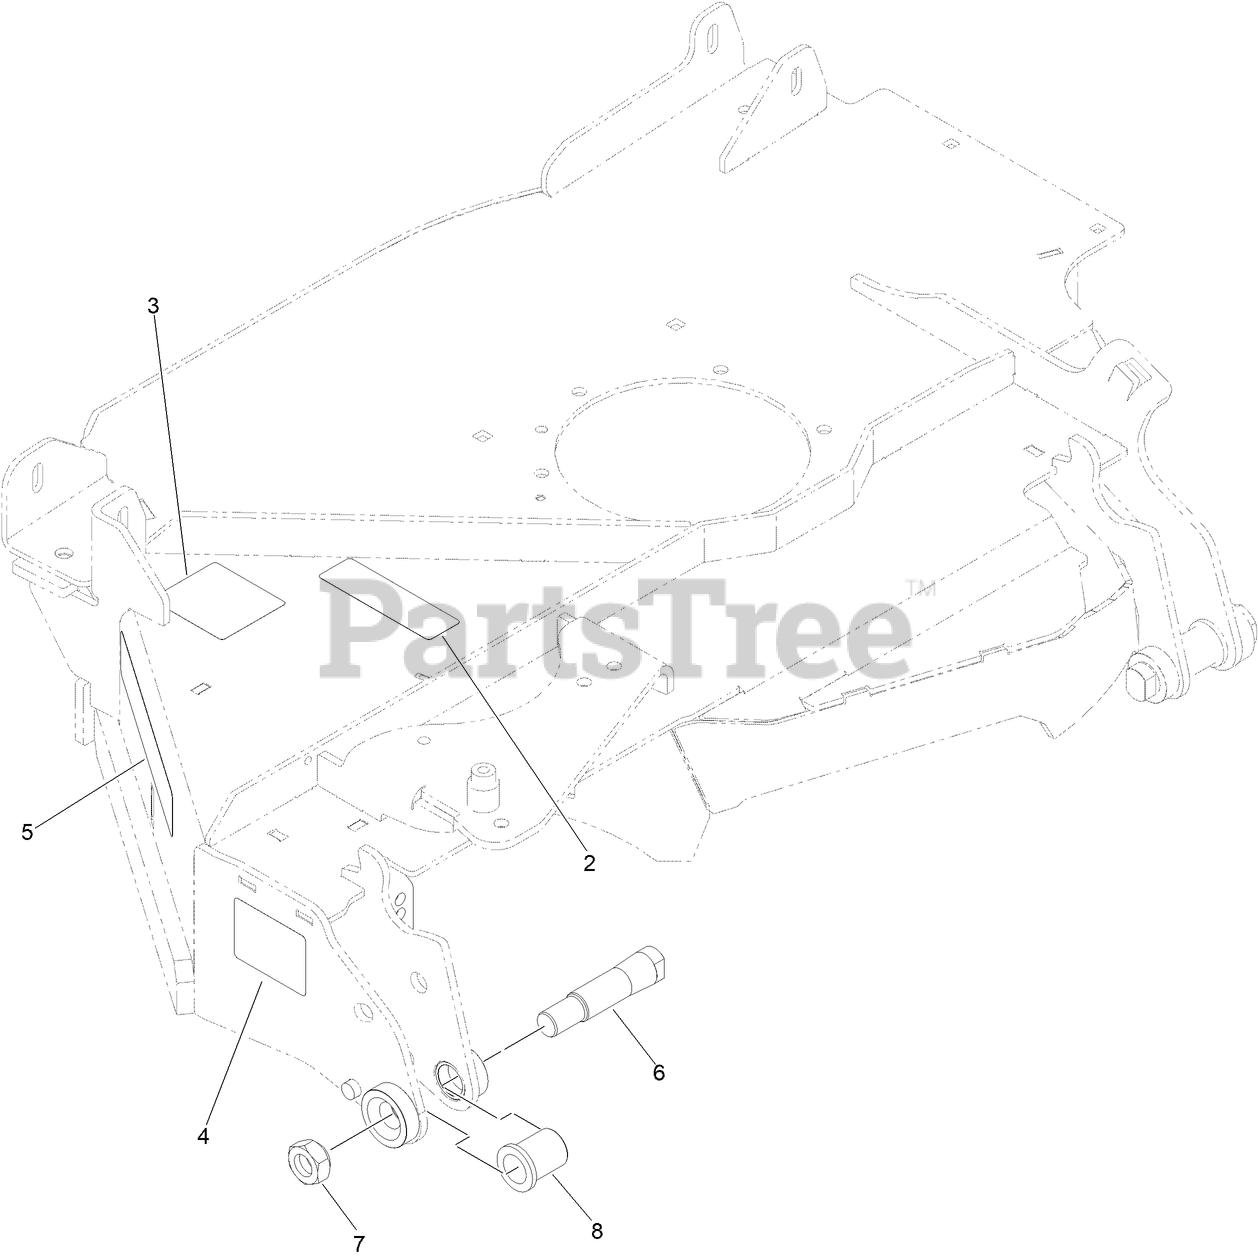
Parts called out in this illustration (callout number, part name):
2	DECAL-COVER, MISSING
3	DECAL-DANGER, THROWN OBJECT
4	DECAL-WARNING, PINCH POINT
6	BOLT-PIVOT PIN
7	NUT-LUG
8	BUSHING-FLANGED
